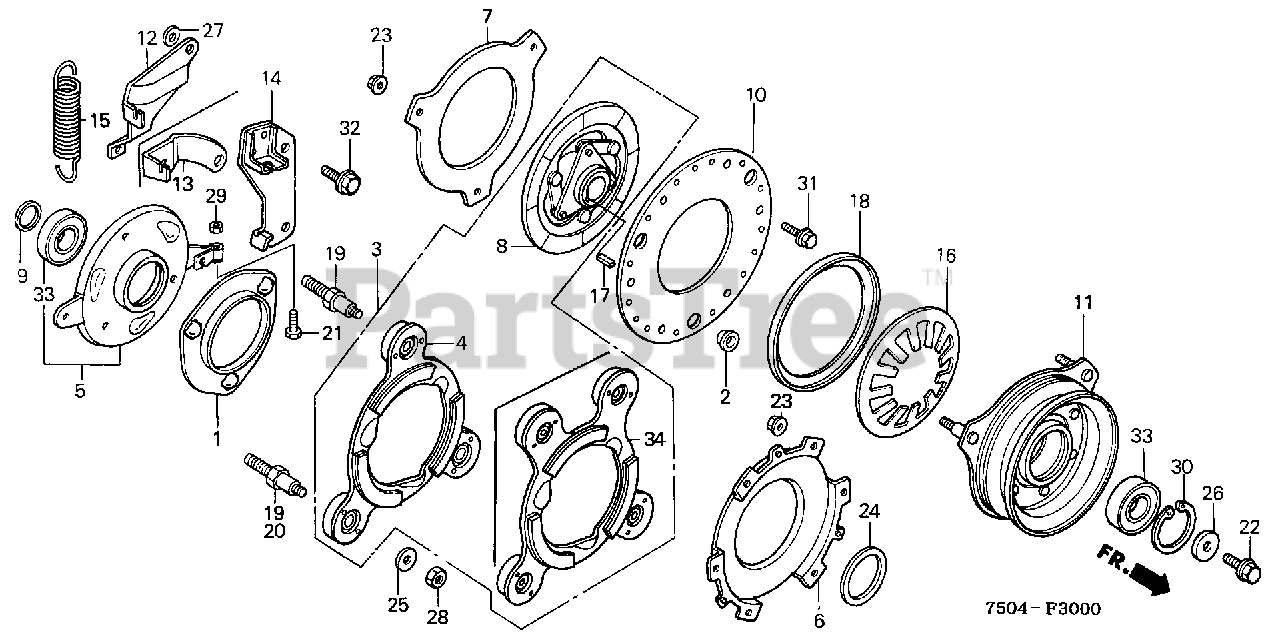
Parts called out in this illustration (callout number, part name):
1	RETAINER, FR. BALL
2	BUSH, RR. CLUTCH
5	PLATE, BALL CONTROL
6	PLATE, BRAKE
7	PLATE, CLUTCH SIDE
8	DISK, FRICTION
9	COLLAR, DISTANCE (25MM)
10	PLATE, CLUTCH
11	PULLEY, DRIVEN
12	HOOK, SPRING
15	SPRING, CLUTCH RETURN
16	SPRING, CLUTCH
17	KEY (7X7X23) (NOT AVAILABLE)
18	SEAT, CLUTCH SPRING
19	BOLT, SPECIAL
21	BOLT, HEX. (8X30)
22	BOLT, SPECIAL (8X25)
23	NUT, U (6MM)
24	SHIM (25X38X1.25) (A)
24	SHIM (25X38X1.3) (B)
24	SHIM (25X38X1.4) (D)
24	SHIM (25X38X1.45) (E)
24	SHIM (25X38X1.5) (F)
24	SHIM (25X38X1.55) (G)
24	SHIM (25X38X1.6) (H)
24	SHIM (25X38X1.65) (I)
24	SHIM (25X38X1.7) (J)
24	SHIM (25X38X1.75) (K)
24	SHIM (25X38X1.1) (L)
24	SHIM (25X38X1.2) (M)
25	WASHER, THRUST (8.5)
26	WASHER (8MM)
27	WASHER (6X17)
28	NUT, HEX. (8MM)
29	NUT, HEX. (8MM)
30	CIRCLIP (INNER) (47MM)
31	BOLT, FLANGE (6X16)
33	BEARING, RADIAL BALL (6005UU)
34	BRAKE ASSY.
